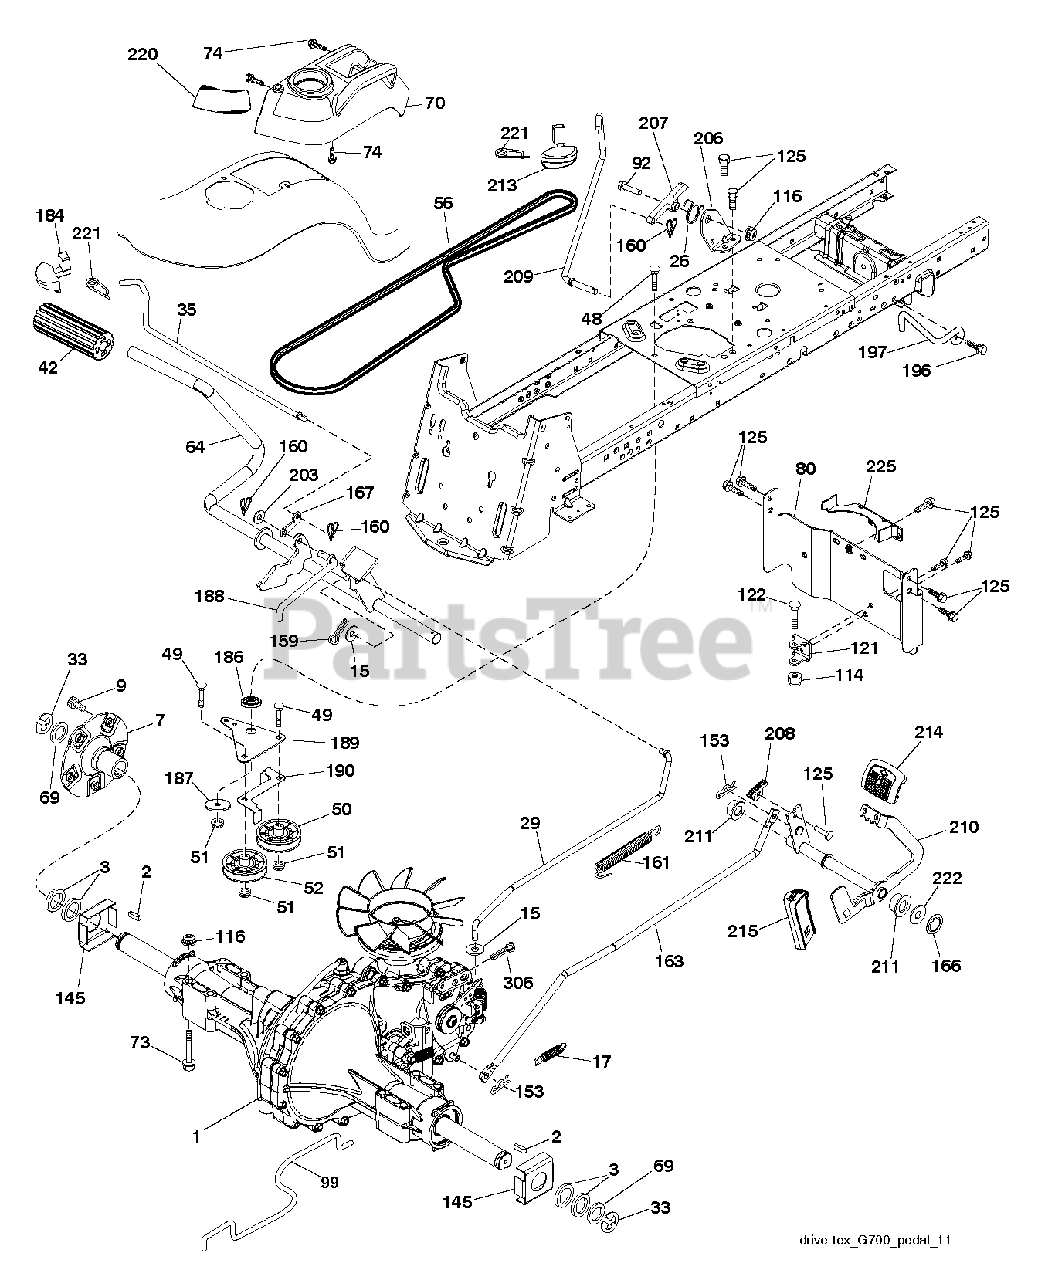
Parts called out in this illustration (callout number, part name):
2	KEY 1/4 X 2.5
7	HUB.ASM.WHEEL.REAR.23"TEX
15	WASHER
17	SPRING.BRAKE.HG3000/3500
26	SPRING.RETURN.CRUISE
33	E RING HYT
35	ROD .BRAKE. PARKING. GT. HUSQ.
42	PEDAL COVER T
48	BOLT.3/8-16X1.50
50	IDLER.FLAT.910.OFFSET
51	NUT LOCK FLG 3/8-16 UNC
52	IDLER.V-GROOVE.910.OFFSET
56	DRIVE BELT, LTH & YTH TRACTORS
64	SHAFT.ASM.PEDAL.BRK.CNTR
70	CONSOLE.ASM.RH.GT.FC.HUSQ
73	BOLT HEX 5/16-18 GR 5
74	SCREW.HI-LO.CONSOLE
80	STRAP.TORQUE.YT.G700
92	BOLT
99	SPRING.BYPASS.YT.G700
114	NUT.71038.31-18.HEX.NYLOCK
116	NUT LOCK HEX FLANGE 5/16-18
121	BRACKET STRAP TORQUE
122	BOLT.5/16-18X2.5
125	SCREW
145	WASHER.AXLE.FLANGE.HG-3000
153	RETAINER M
159	COTTER PIN
160	RETAINER CLIP
161	SPRING, RETURN LT
163	ROD PEDAL CONTROL
166	NUT.PUSH.625
167	LATCH.BRAKE.SPRING
184	RB HANDLE.PARKG.BRK.HUS/PRED
186	SPACER.RETAINER
187	WASHER 12/32X2X10GA
188	RP LINK.CLUTCH.GROUND.DRIVE
189	BELLCRANK.GROUND.DRIVE.TRAPPED
190	KEEPER BELLCRANK ROUND DRIVE
196	SCREW 3/8-16X1
197	BRKT.ANIT-ROTATION.CLUTCH
203	WASHER
206	BRACKET.MOUNT.CRUISE.LATCH
207	LATCH.CONTROL.CRUISE
208	GEAR.SECTOR.CONTROL.CR
209	ROD.CONTROL.CRUISE.GT.
210	ROCKER.ASM.PEDAL.CONTR
211	BEARING.NYLON
213	KNOB.CONTROL.CRUSIE.HU
214	PEDAL.FORWARD.PAD.TEX
215	PEDAL.REVERSE.TEX.GT.4
220	REFLECTOR.RH.TEX GT
221	RETAINER.SPRING.CLIP.H
222	WASHER 21/32 X 1-1/4 X 10 GA.
225	KEEPER.T/A.YT.G700
306	PIN COTTER
